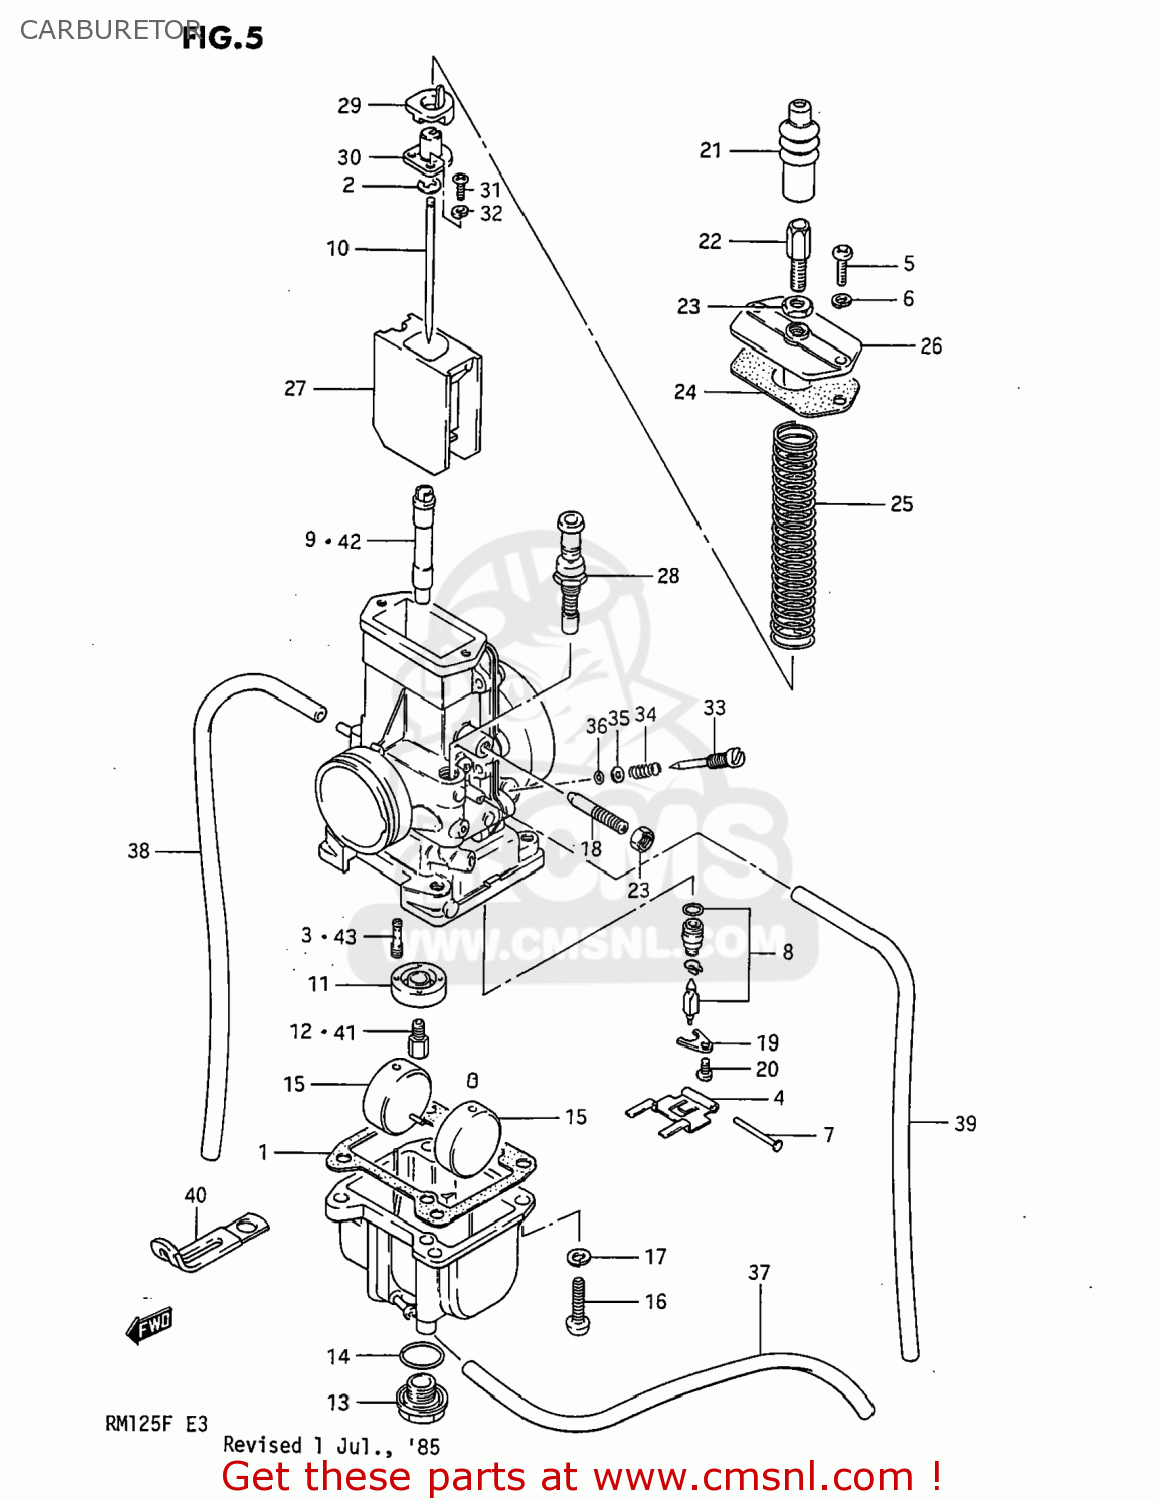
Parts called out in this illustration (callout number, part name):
1	GASKET,FLOAT CAHMBER (NAS)
2	CLIP
3	JET,PILOT(45)
4	ARM,FLOAT
5	SCREW
6	LOCK WASHER
7	PIN,FLOAT
8	VALVE ASSEMBLY,NEEDLE
9	JET
10	NEEDLE JET
11	RING,MAIN JET FIXING
12	JET
13	SCREW,GUIDE
14	O RING,DRAIN PLUG
15	FLOAT
16	SCREW
17	LOCK WASHER
18	SCREW,THROTTLE SCREW
19	PLATE
20	SCREW
21	CAP,CABLE ADJUSTER
22	ADJUSTER,CABLE
23	NUT
24	GASKET,TOP (NAS)
25	SPRING,THROTTLE VALVE
26	CAP,CARBURETOR,TOP
27	VALVE,THROTTLE
28	PLUNGER ASSEMBLY
29	RING
30	JOINT
31	SCREW
32	LOCK WASHER
33	SCREW,PILOT AIR
34	SPRING,THROTTLE SCREW
35	GASKET
36	O-RING
37	HOSE
38	HOSE
39	HOSE
40	CLAMP L:35
41	JET
42	JET,NEEDLE
43	JET
